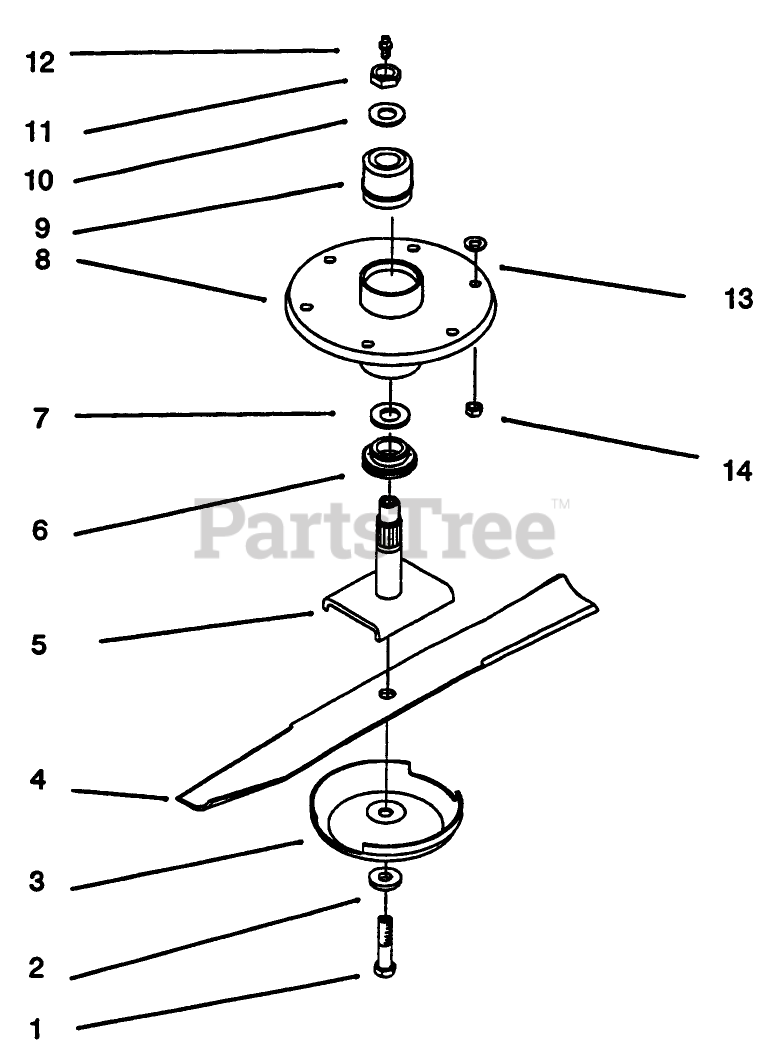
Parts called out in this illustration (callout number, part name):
1	SCREW-BLADE
2	WASHER
3	CUP-SCALP, ANTI
4	Blade
5	Shaft-Spindle
6	SPACER
7	SEAL-OIL
8	HOUSING-SPINDLE
9	BEARING ASM
10	WASHER
11	NUT-HEX
12	FITTING-GREASE
13	WASHER-FLAT
14	NUT-HF
